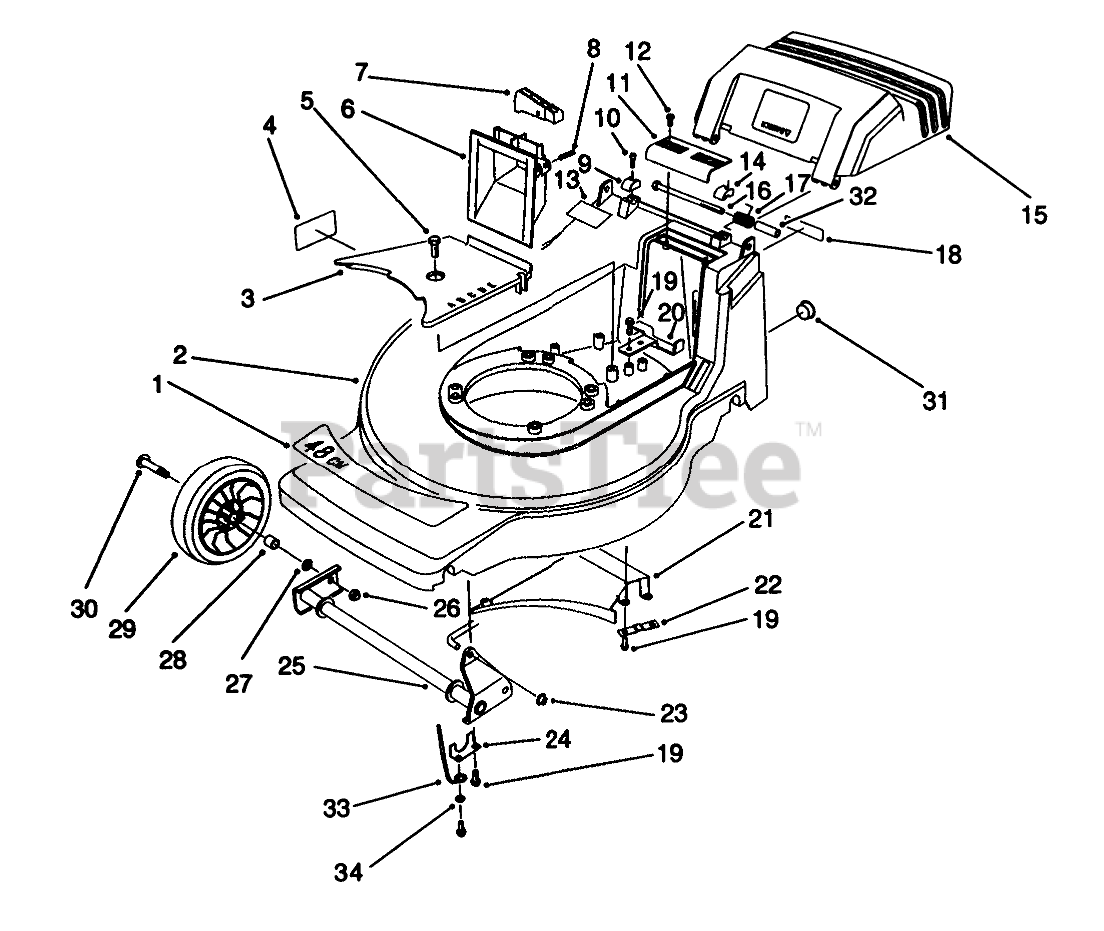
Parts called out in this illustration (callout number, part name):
1	DECAL - DECK
2	Housing-48cm (Incl. Ref. #4, & 13)
3	BELT COVER
4	Decal Danger
5	SCREW-HWHTF
6	GRIP - LOWER
7	TRIGGER - HOC
8	PIN-SPIRAL
9	CAP-HINGE BOLT, RH
10	SCREW-HSH
11	GRIP-UPPER
12	SCREW-PPH, PLASTITE
13	Decal-Noise
14	CAP-HINGE BOLT, LH
15	Door-Discharge
16	SCREW-HH
17	DOOR SPRING
18	DECAL FRENCH REGUL.
19	SCREW-HWHTF
20	REAR BELT GUIDE
21	Ramp-Discharge
22	Strap-Rear Suspension
23	NUT-PUSH
24	FRONT SECURING PLATE
25	FRONT PIVOT WA
26	Nut
27	WASHER
28	BUSHING
29	Wheel & Tire Assembly (Incl. Ref. #28)
30	BOLT-WHEEL
31	DOME PLUG (DP-1000)
32	SPACER-DOOR
33	LH AXLE RETAINER
34	WASHER-FLAT
